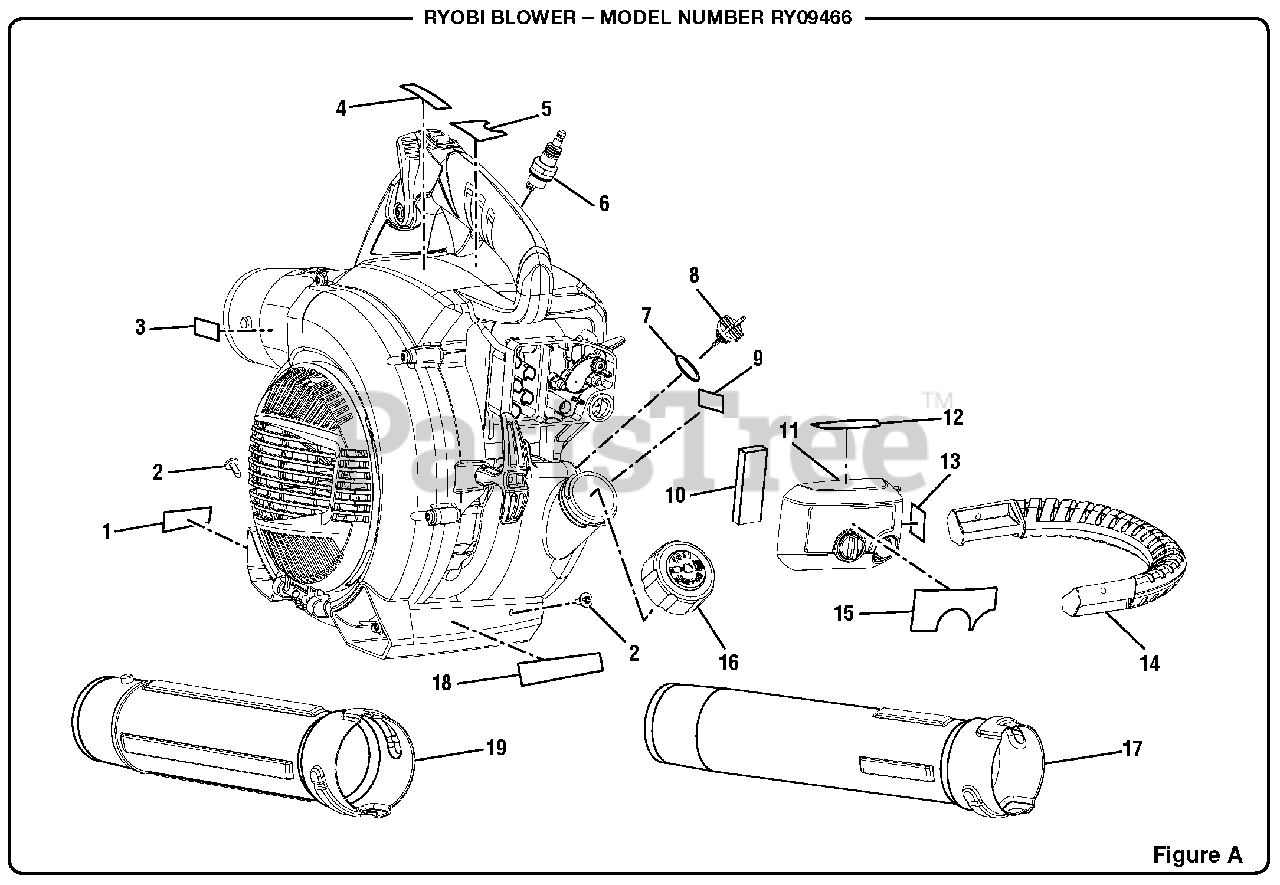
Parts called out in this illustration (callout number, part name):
1	Combustion Warning Label
2	Screw (#10-14 x 1/2 in., T25 Torx Truss Hd. T.F.)
3	Logo Label
4	Warning Label
5	Logo Label
6	Spark Plug (Champion RY4C)
8	Oil Fill Cap w/Dipstick
9	Add Oil Label
11	Air Filter Cover
12	Stop Label
13	Run/Start Label
15	Starting Label
16	Fuel Cap Assembly
17	Sweeper Nozzle
18	No Mix Label
19	Upper Blower Tube
